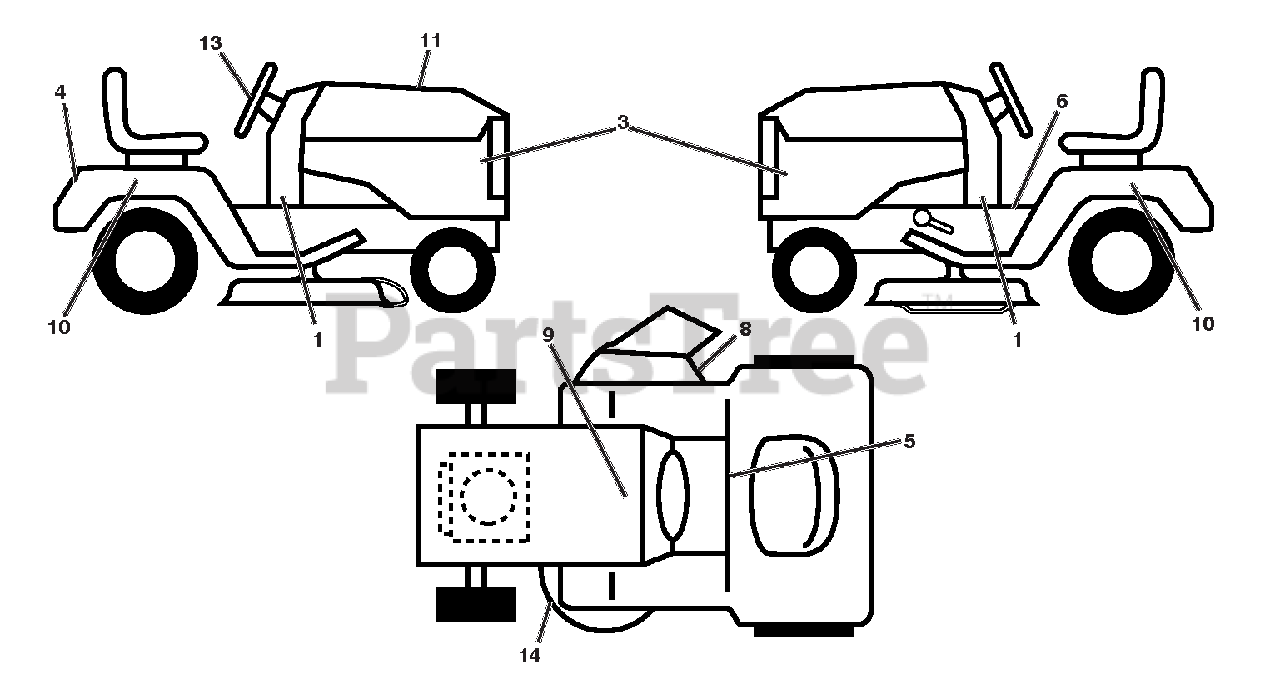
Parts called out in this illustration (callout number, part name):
1	DECAL.DASH
3	DECAL.SDPNL.PWRDBY KOHL.ARIENS
4	DECAL.FENDER.REAR.ARIENS
5	DECAL.FENDER
6	DECAL, FENDER.WARNING
8	DECAL.WARNING.KEEP.HAND.AWY
9	DECAL.BAT.DAN/POI P/L SYM.WPN
10	DECAL.FENDER.SIDE.HYDRO
11	DECAL REPLACEMENT
13	DECAL.WHEEL.STEER.ARIENS
14	DECAL.V-BELT.SCH.
